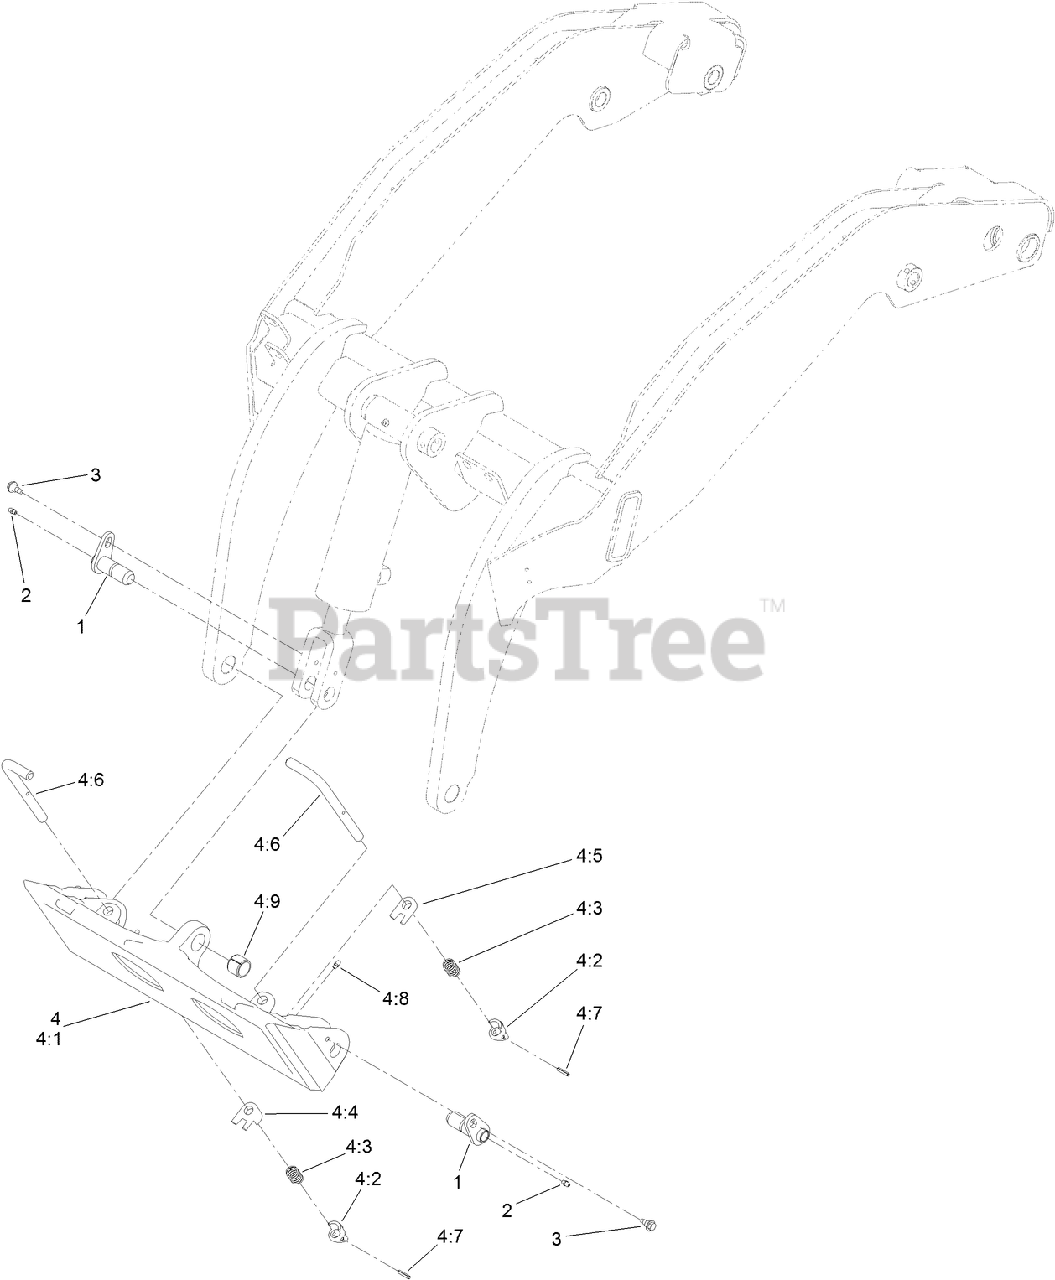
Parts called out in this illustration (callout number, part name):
1	PIN-PIVOT
2	FITTING-GREASE
3	BOLT-SHOULDER
4	QUICK ATTACH ASM
4:1	MOUNT-QTACH
4:3	SPRING-COMPRESSION
4:4	STOP-RH
4:5	STOP-LH
4:6	PIN-LOCKING
4:7	PIN-GROOVED
4:8	FITTING-GREASE
4:9	BUSHING-TENSION
